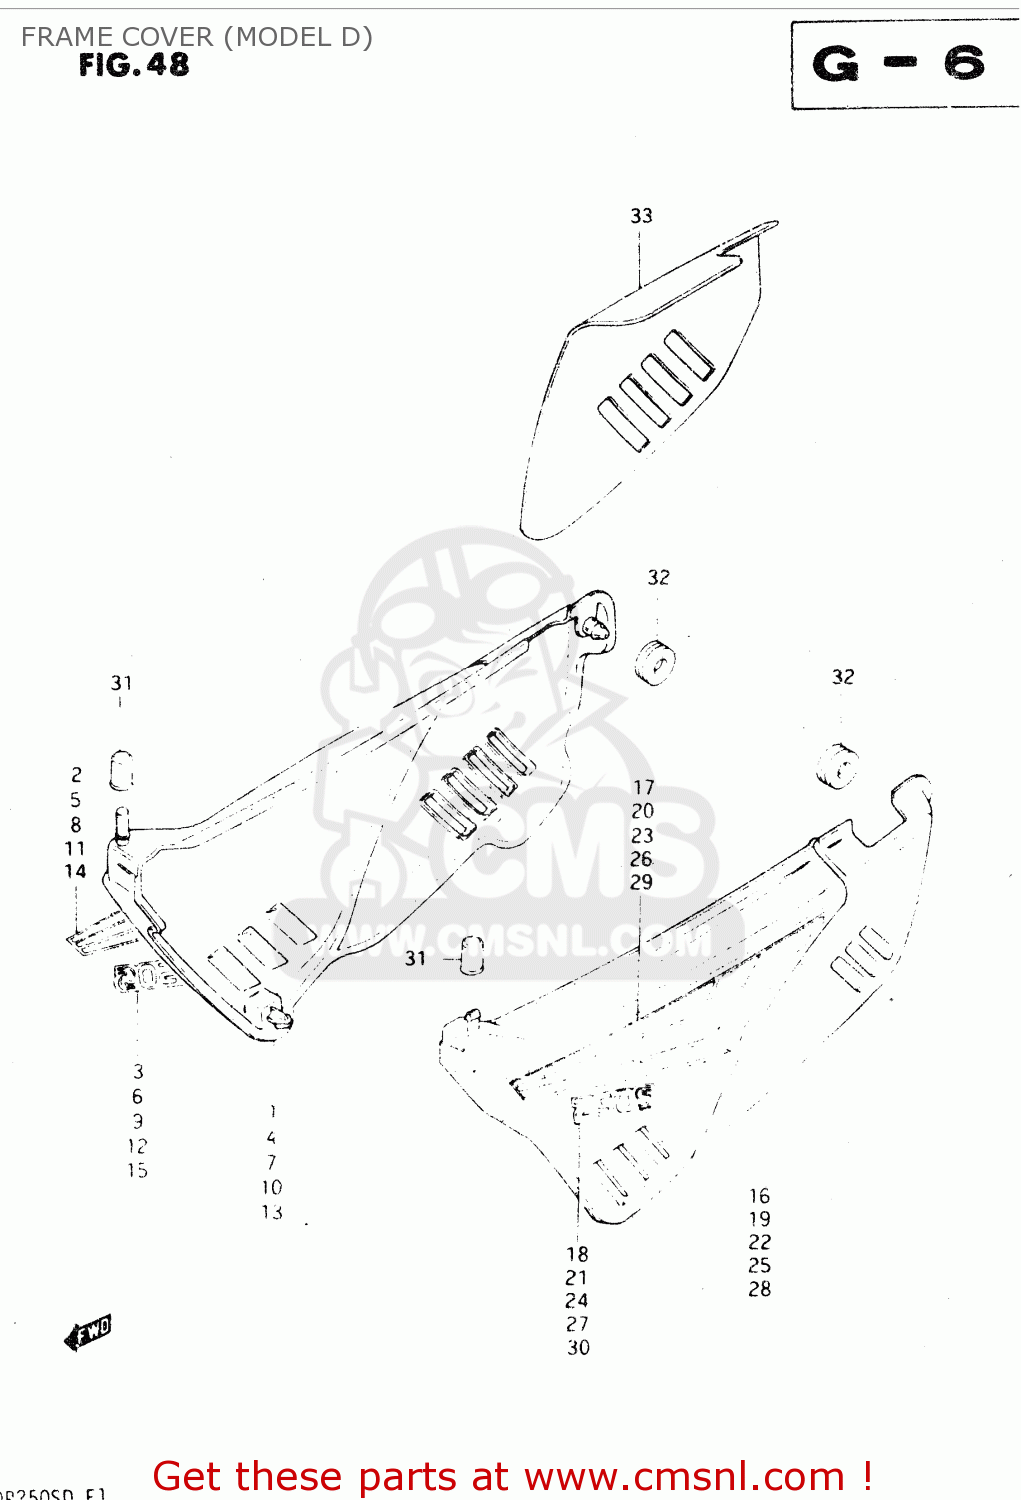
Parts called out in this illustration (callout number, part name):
1	COVER, FRAME RH (BLACK)
2	TAPE SET, FRAME COVER RH
3	EMBLEM, LH
4	COVER, FRAME RH (BLUE)
5	TAPE SET, FRAME COVER RH
6	EMBLEM, LH
7	COVER,FRAME,RIGHT
8	TAPE SET, FRAME COVER RH
9	EMBLEM, LH
10	COVER, FRAME RH (WHITE)
11	TAPE,FRAME COVER,RIGHT
12	EMBLEM
13	COVER, FRAME RH (YELLOW)
14	TAPE SET, FRAME COVER RH
15	EMBLEM
16	COVER, FRAME LH (BLACK)
17	TAPE SET, FRAME COVER LH
18	EMBLEM, LH
19	COVER, FRAME LH (BLUE)
20	TAPE SET, FRAME COVER LH
21	EMBLEM, LH
22	COVER,FRAME,LEFT
23	TAPE SET, FRAME COVER LH
24	EMBLEM, LH
25	COVER, FRAME, LH
26	TAPE,FRAME COVER,LEFT
27	EMBLEM
28	COVER, FRAME LH (YELLOW)
29	TAPE SET, FRAME COVER LH
30	EMBLEM
31	CUSHION
32	CUSHION
33	HEAT SHIELD,FRAME COVER
